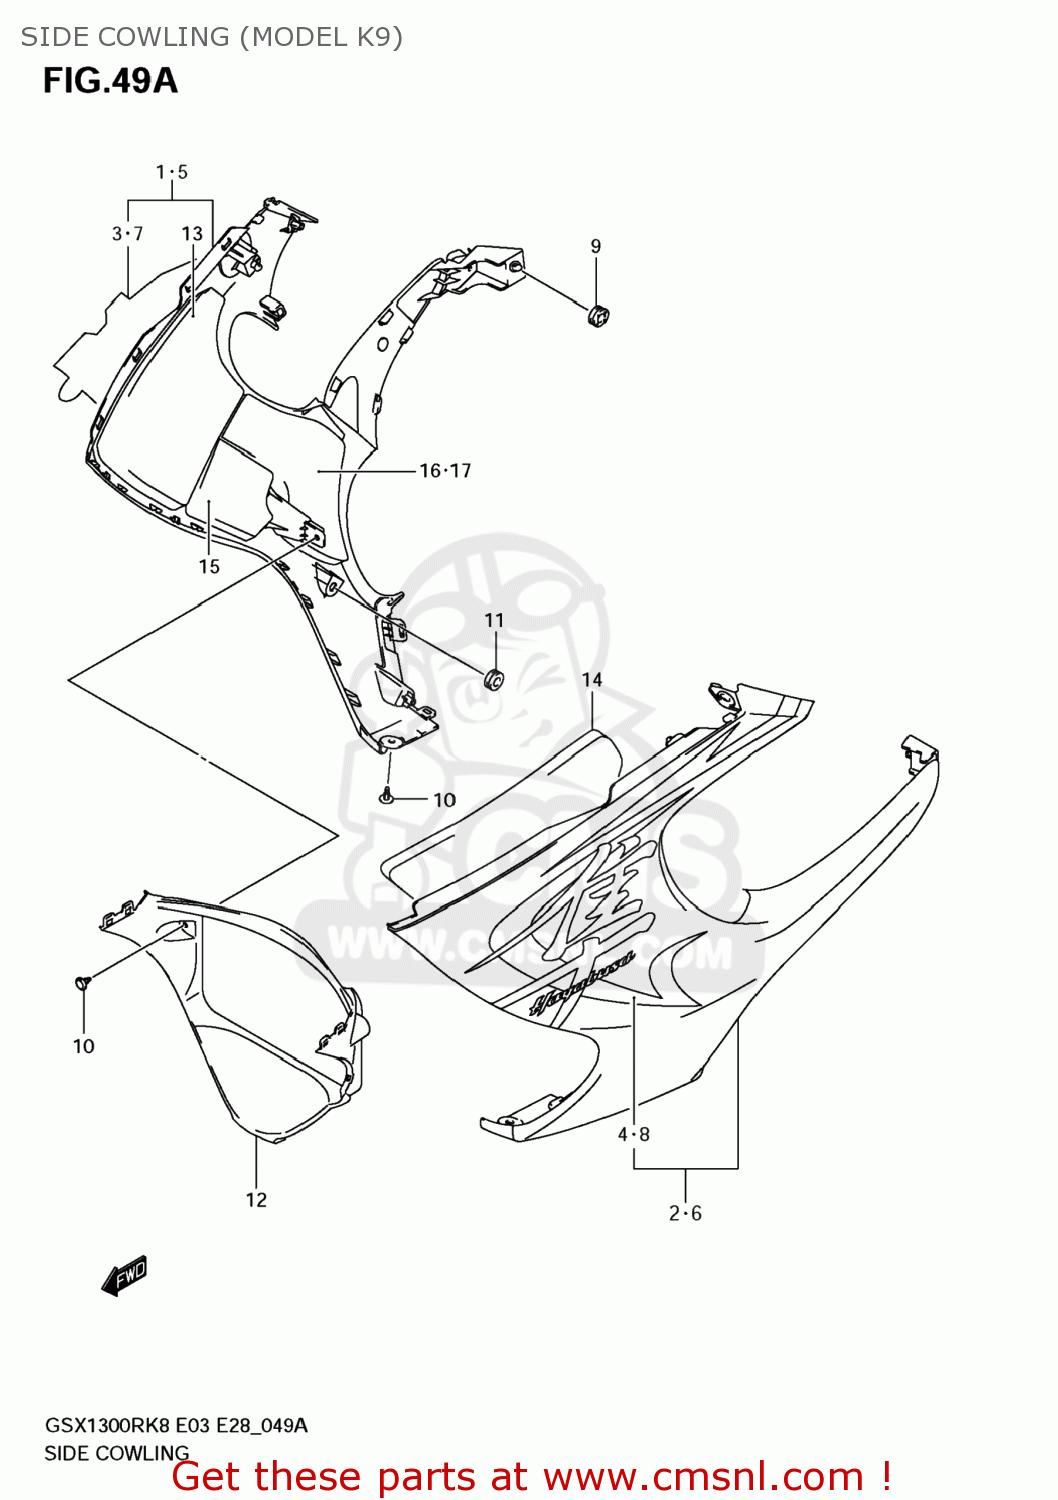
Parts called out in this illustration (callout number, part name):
1	COWLING COMP,S
2	COWLING COMP,S
3	TAPE SET,COWL SIDE,R
4	TAPE SET,COWL SIDE,L
5	COWLING,SIDE,R
6	COWLING COMP,S
7	TAPE SET,COWL SIDE,R
8	TAPE SET,COWL SIDE,L
9	CUSHION
10	CLIP
11	CUSHION
12	COWLING,UNDER CTR
13	CUSHION,SIDE COWL,R
14	CUSHION,SIDE COWL,L
15	CUSHION,SIDE COWL
16	SHIELD,SIDE COWL,R
17	SHIELD,SIDE COWL,L
